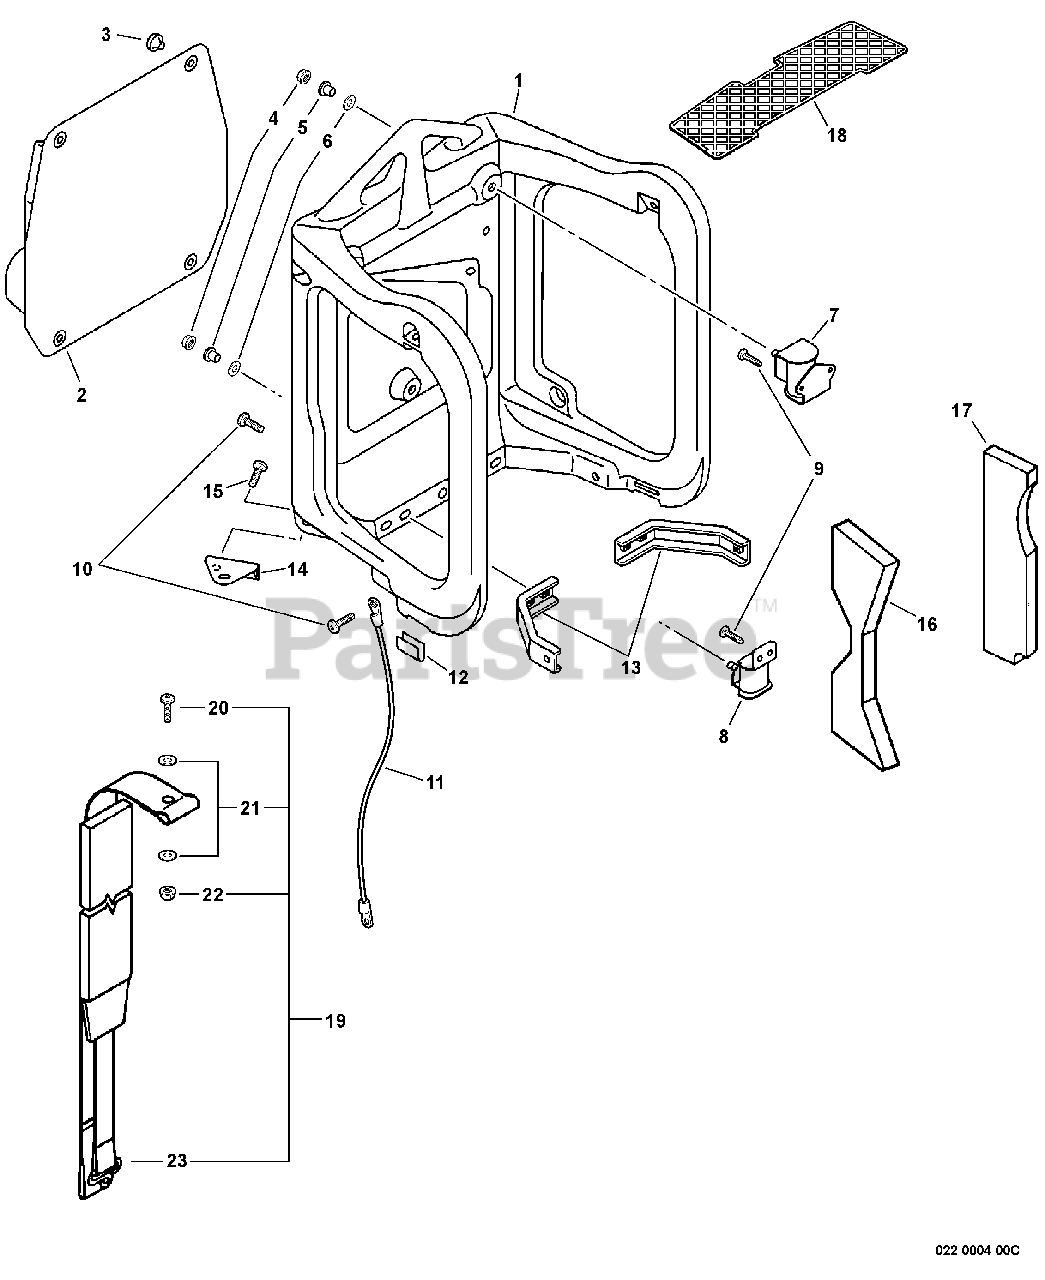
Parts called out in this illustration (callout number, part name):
1	FRAME, BACKPACK
2	CUSHION, BACKPACK
4	NUT - 5 -- FLANGE
6	WASHER - RUBBER
8	CUSHION
9	SCREW - 5X16 -- TAPPING
10	SCREW - 5X14
11	LEAD - GROUND
12	BUMPER
13	CONNECTOR, FRAME
14	BRACKET, HANGER
15	SCREW - 5X20
16	PAD, FOAM - LEFT
17	PAD, FOAM - RIGHT
18	GAURD, DEBRIS
19	BACKPACK STRAP ASSY
20	SCREW - 5X14
22	NUT - 5 -- FLANGE
